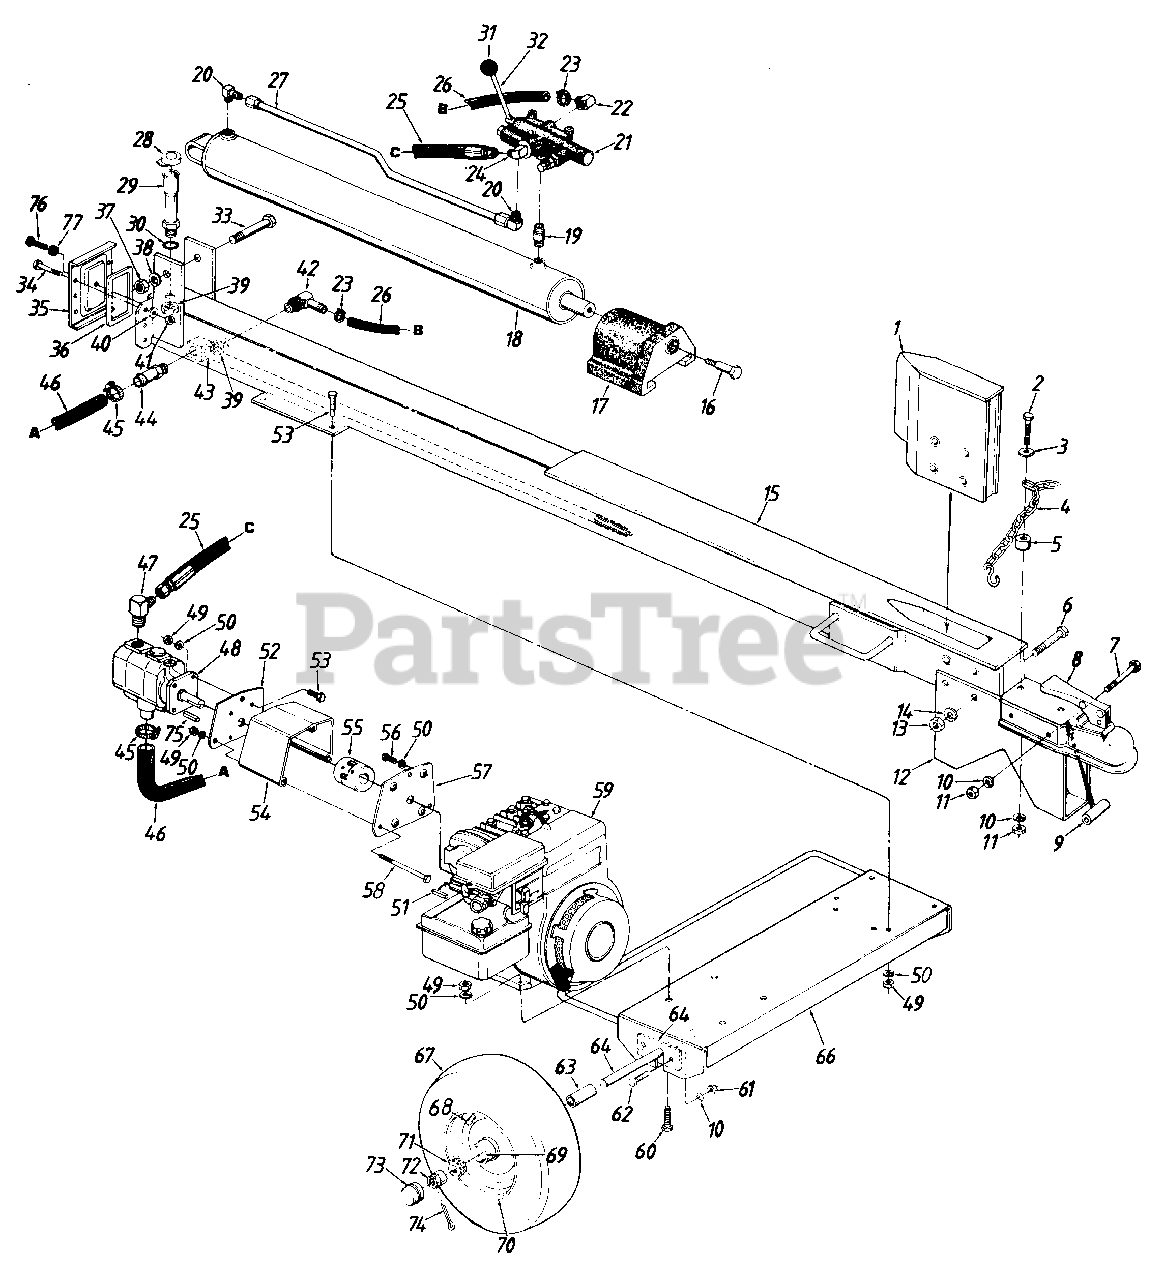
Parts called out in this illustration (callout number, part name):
1	Wedge Ass'y.
2	Hex Bolt 3/8-16 x 1.5" Lg. (Grade 5)
3	Fl-Wash. .375" I.D. x .87" O.D.
4	Chain Tow Hitch
5	Spacer .38" I.D. x .625" O.D.
6	Hex Bolt 5/8-18 x 3.5" Lg.
7	Hex Bolt 3/8-16 x 3.25" Lg. (Grade 8)
8	Tow Hitch Ass'y.
9	Spacer .375" I.D. x .625" O.D.
10	L-Wash. 3/8" I.D.
11	Hex Nut 3/8-16 Thd. (Grade 5)
12	Beam Stand
13	Hex Nut 5/8-18 Thd.
14	L-Wash. 5/8" I.D.
15	Oil Tank Ass'y.
16	Shld. Bolt .62n Dia. x .475"
17	Pusher Plate
18	Hydraulic Cylinder
19	Pipe Nipple 1/2" NPT x 2" Lg.
20	90ø Solid Male Adapter
21	Control Valve
22	Return Elbow
23	Adjustable Hose Clamp
24	90ø Solid Male Adapter
25	High Pressure Hydraulic Hose 29.5" Lg.
26	Return Hose 3/4" I.D. x 23l/2" Lg.
27	Metal Pressure Tube
29	Filler Tube Ass'y.
30	"O"-Ring.92" I.D.
31	Ball Knob
32	Control Handle
33	Hex Bolt 3/4-10 x 4.5" Lg.
34	Hex Bolt 5/16-18 x 1.5" Lg.
35	Beam End Plate
36	Gasket
37	Hex Nut 3/4-10 Thd.
38	L-Wash. 3/4" I.D.
39	Hex Nut 1-1/16-12 Thd.
40	Fl-Wash. .34" I.D. x .68" O.D.
41	Hex L-Nut 5/16-18 Thd.
42	90ø Adapter 3/4" Hose
43	Strainer Tube Ass'y.
44	Adapter 1" x 1-1/16-12 Thd.
45	Hose Clamp 5/8"
46	Suction Hose 1" I.D.
47	90ø Adapter
48	Two Volume Pump
49	Hex Nut 5/16-24 Thd.
50	L-Wash. 5/16" I.D.
51	Sq. Key 3/16 x .75" Lg.
53	Hex Bolt 5/16-24 x 1.0" Lg.*
54	Coupling Shield
55	Flexible Coupling
56	Hex Bolt 5/16-24 x .62" Lg.
58	Hex Bolt 5/16-24 x 4.0" Lg.
59	Engine
60	Hex Bolt 5/16-24 x 1.75" Lg.
61	Hex Nut 3/8-24 Thd.
62	Hex Bolt 3/8-24 x 1.0" Lg.
63	Spacer .75" I.D. x 1.12" O.D.
64	Axle Assembly
66	Engine Frame Ass'y.
68	Air Valve
69	Bearing Seal
71	Roller Bearing w/Race
72	Hex Slotted Nut 3/4-16 Thd.
73	Hub Cap
74	Cotter Pin 5/32" Dia.
75	Hi-Pro Key 1/8" x 1/2" Lg.
76	Hex TT-Tap Scr. 5/16-18 x .62" Lg.
77	Gasket Washer 5/16" I.D. x 3/4" O.D.
